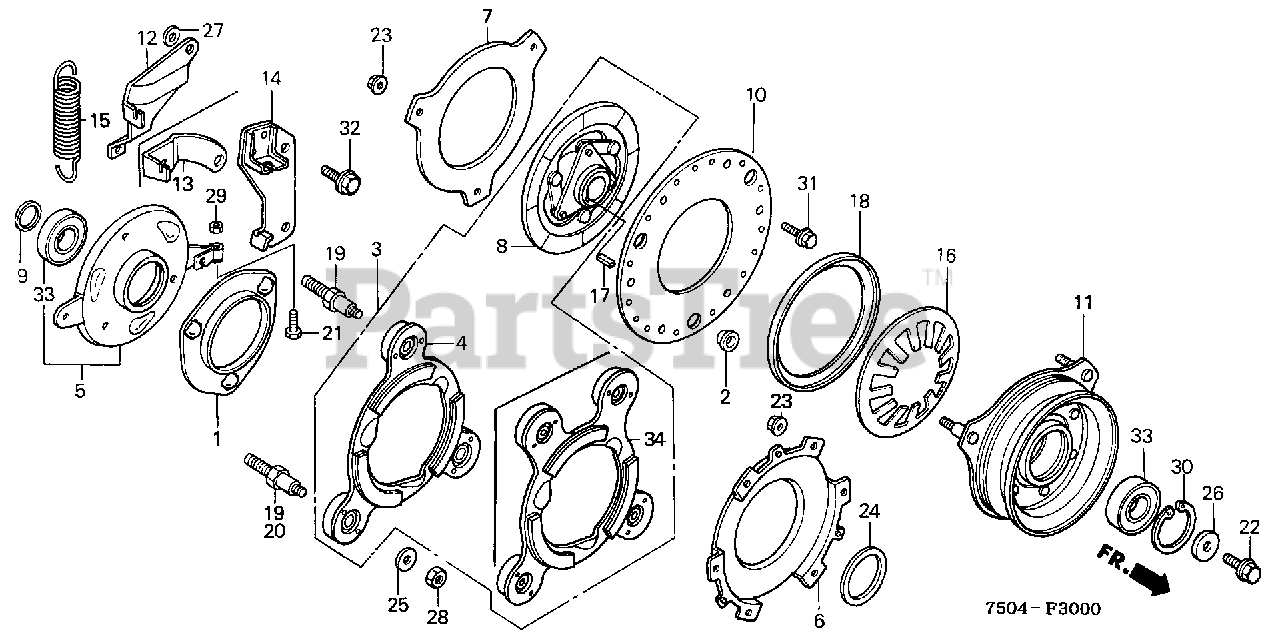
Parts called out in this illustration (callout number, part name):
1	RETAINER, FR. BALL
2	BUSH, RR. CLUTCH
3	DISK SET, BRAKE & FRICTION
4	BRAKE ASSY.
5	PLATE, BALL CONTROL (NOT AVAILABLE)
6	PLATE, BRAKE
7	PLATE, CLUTCH SIDE
9	COLLAR, DISTANCE (25MM)
10	PLATE, CLUTCH
11	PULLEY, DRIVEN (NOT AVAILABLE)
13	HOOK, SPRING
15	SPRING, CLUTCH RETURN
16	SPRING, CLUTCH
17	KEY (7X7X23) (NOT AVAILABLE)
18	SEAT, CLUTCH SPRING
19	BOLT, SPECIAL (NOT AVAILABLE)
20	BOLT, SPECIAL (NOT AVAILABLE)
22	BOLT, SPECIAL (8X25)
23	NUT, U (6MM)
25	WASHER, THRUST (8.5)
26	WASHER (8MM)
28	NUT, HEX. (8MM)
30	CIRCLIP (INNER) (47MM)
31	BOLT, FLANGE (6X16)
33	BEARING, RADIAL BALL (6005UU)
